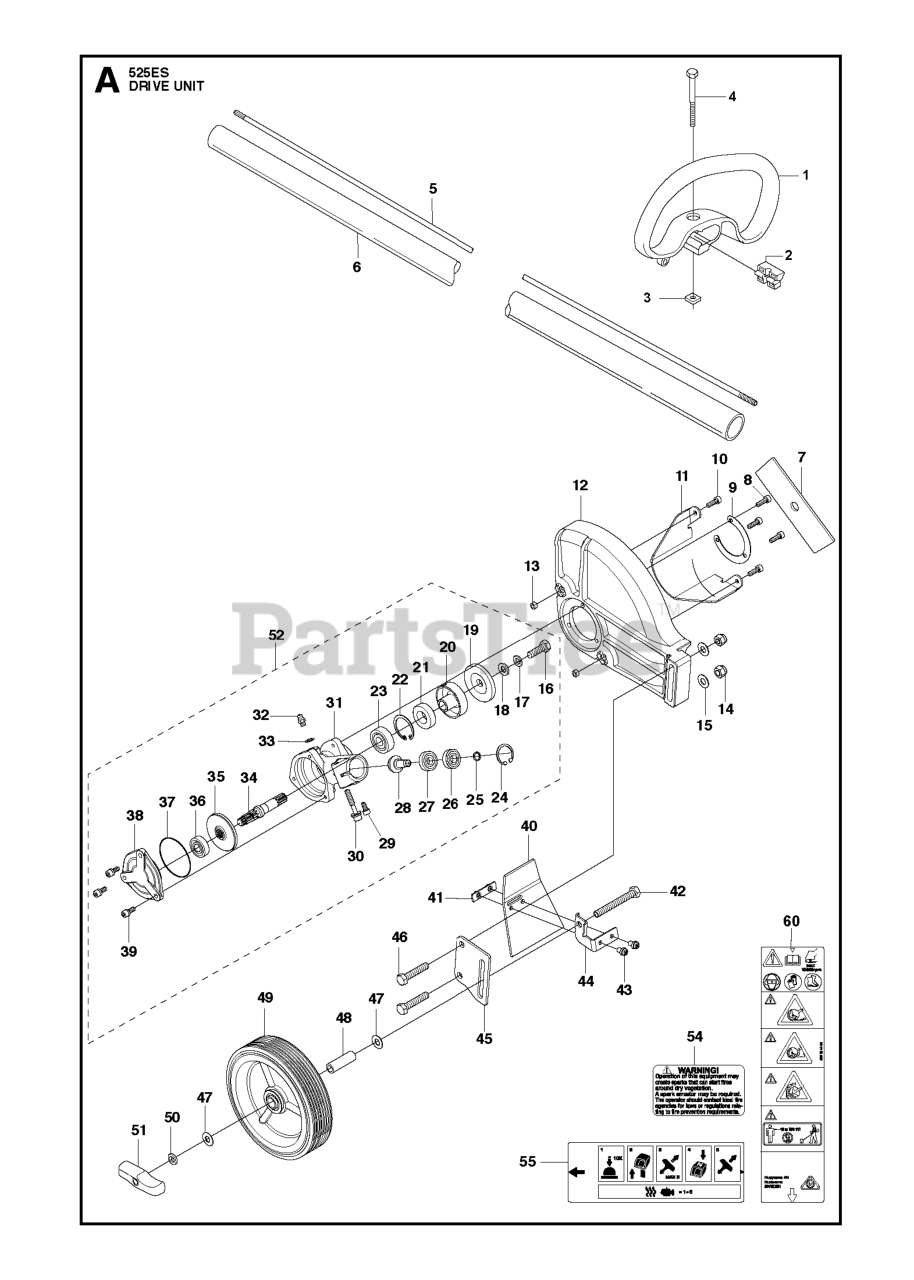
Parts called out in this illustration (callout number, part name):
2	SPACER PLASTIC
5	DRIVESHAFT
7	BLADE 7.52X2X.125
11	Protection
14	NUT
16	BOLT M8 X L25 L/H
19	HOLDER (B)
20	HOLDER (A)
24	RP_RING
42	BOLT M8 X L65
45	MAIN BRACKET
46	BOLT M8 X L40
52	GEAR CASE ASSY
53	LABEL WARNING TRIMMERS AND BRU
54	DECAL SPARK ARRESTOR WARNING
55	DECAL START REMINDER 523/525
